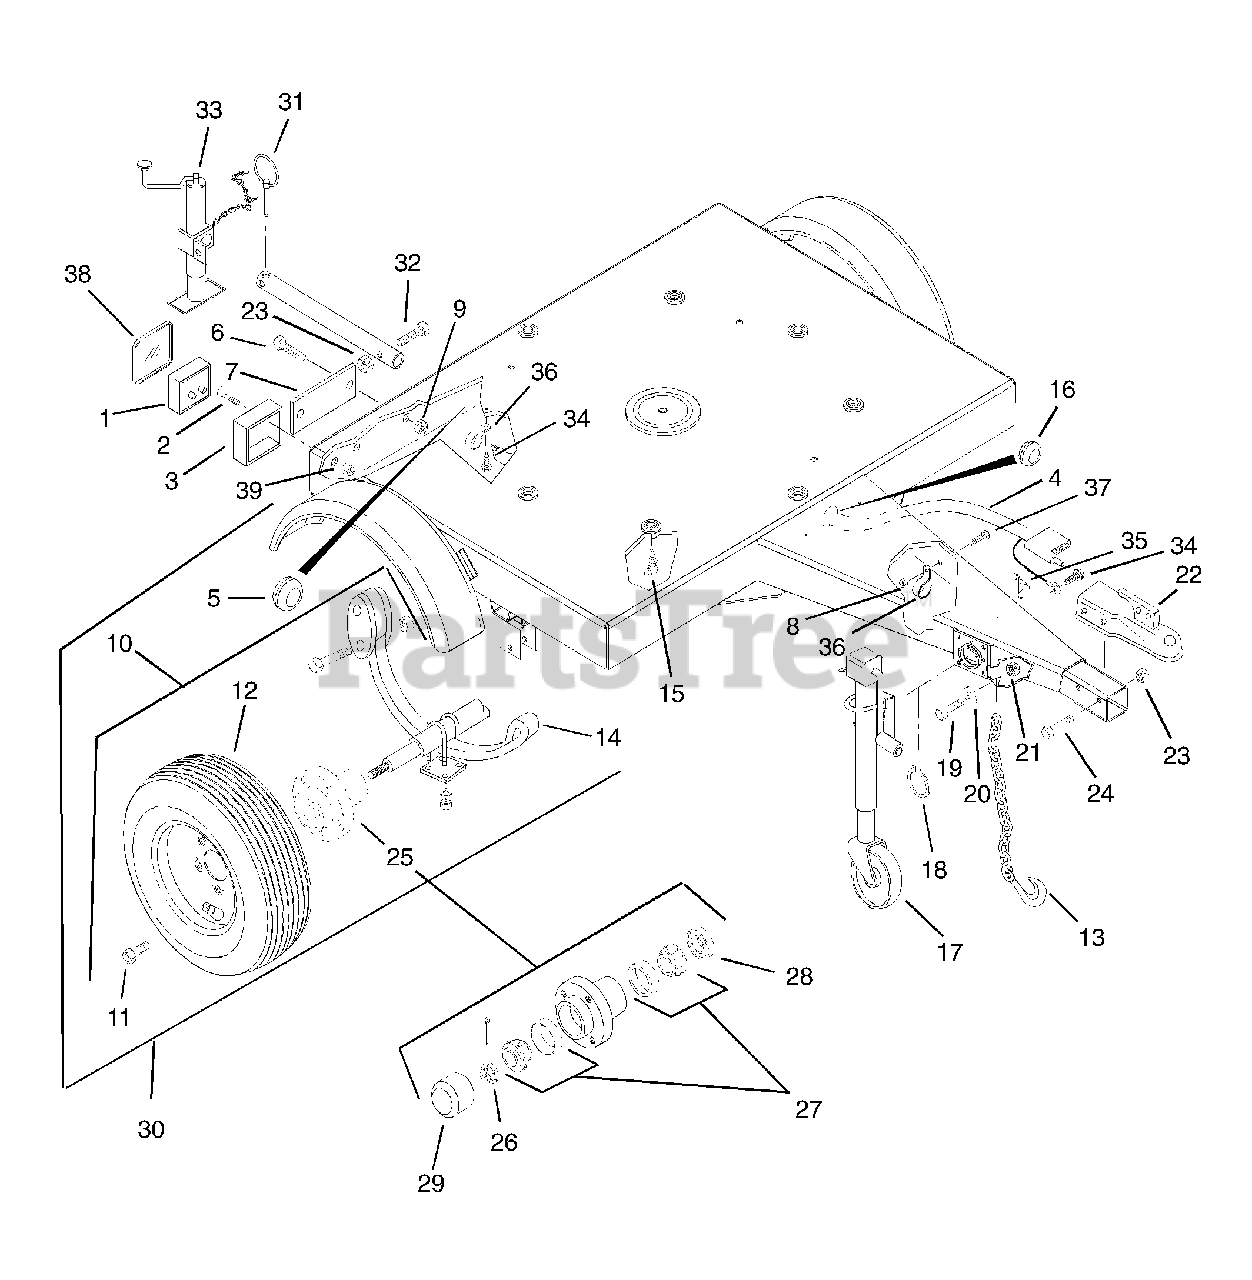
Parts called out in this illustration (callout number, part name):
1	Taillight-Left Hand
1	Taillight-Right Hand
2	Screw-Machine-Flat .25 X .75
3	Left Taillight Weldment
3	Right Taillight Weldment
4	Wire Harness
5	Grommet .188 X .375 ID
6	Screw-Machine-Hex Head 10-24 X .75
7	Reflector
8	Nut-Locking-Center .25-20
9	Nut-Locking-Nylon 10-24 w/Insert
10	Trailer Axle-Complete - Less Tire and Wheels
11	Bolt-Hex .50-20 x .75 x 1.62 Plated
12	Tire/Wheel Assembly
13	Safety Chain
14	Spring-Axle-Service Assembly
15	Fitting-Hydraulic Drive
16	Grommet .75 X 1.06 X 1.38
17	Jack Assembly
18	Ring-Retaining-External 2.500 X .078
19	Bolt-Hex .44-14 X 1.00 Grade 5
20	Washer-Flat-Steel .50 x 1.25 x .083
21	Nut-Locking-Center .44-14
22	Coupler-2" Ball Type
23	Nut-Locking-Center .50-13
24	Bolt-Hex .50-13 x 3.75 Grade 5
25	Hub (Contains 27,28,29)
26	Nut-Slotted 1.0-14
27	Replacement Bearing Assembly
30	Trailer
31	Tube-Jack-Pivot
32	Bolt-Hex .50-13 x 3.00 Grade 5
33	Jack-2000 Lb x 12.75 Screw
34	Screw-Tapping .25 x .50 HWH
35	Clamp-Cushioned Steel
37	Bolt-Hex .25-20 x .75 Grade 5
38	Lens-Tail Light
39	Nut-Locking-Nylon .250-20
